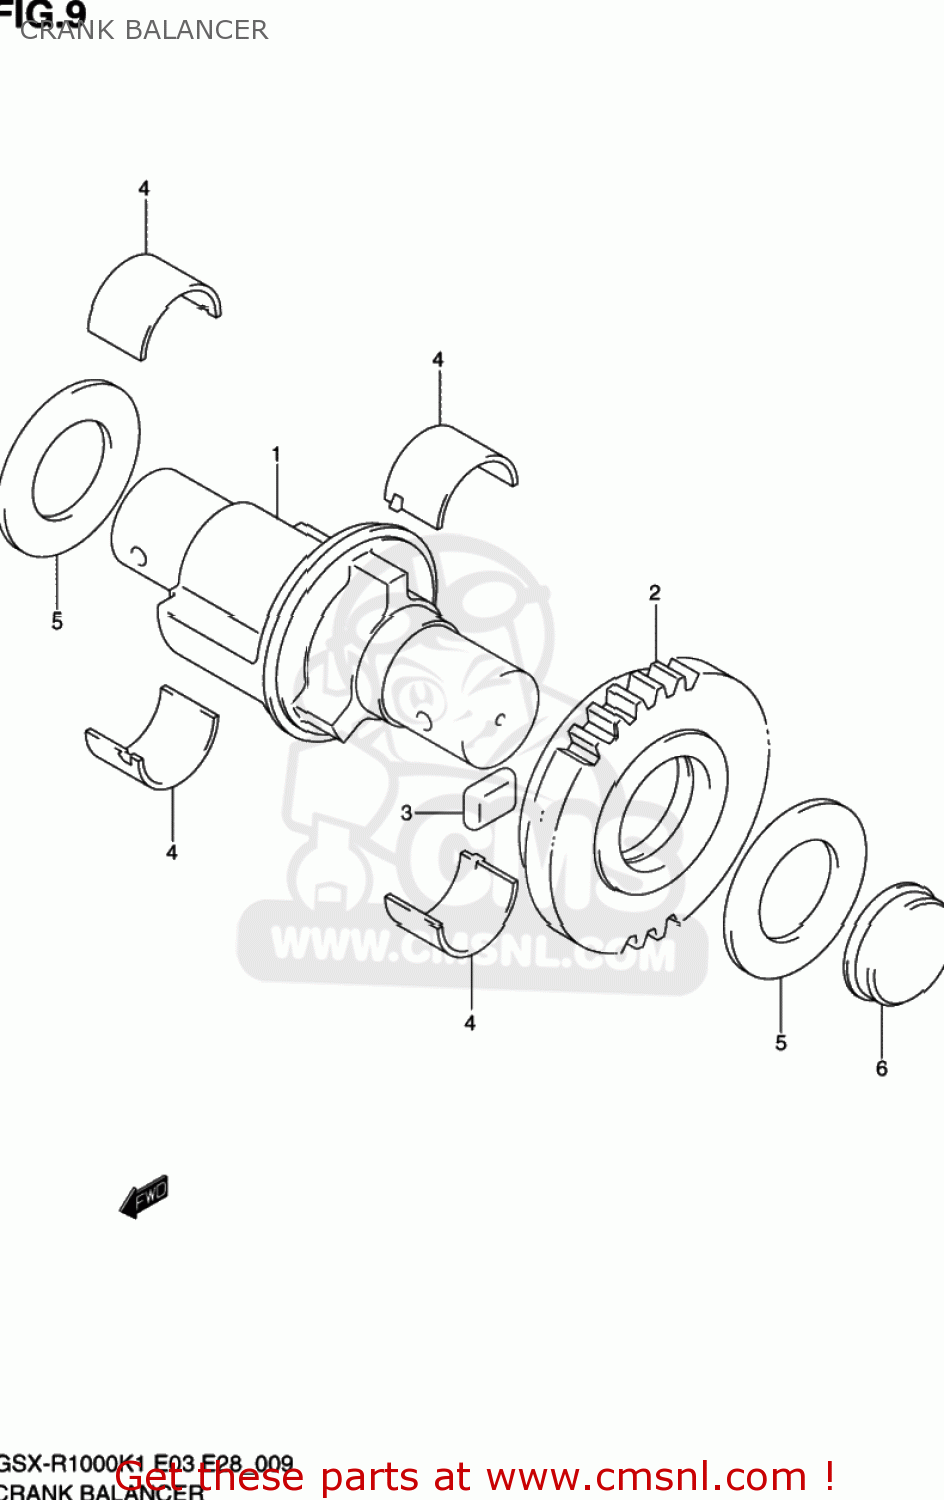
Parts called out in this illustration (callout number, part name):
1	BALANCER,CRANK
2	GEAR,CRANK BALANCER
3	DAMPER,CRANK BALANCER GEAR
4	BEARING,CRANK BALANCER
5	SHIM(23X40X2)
6	PLUG
